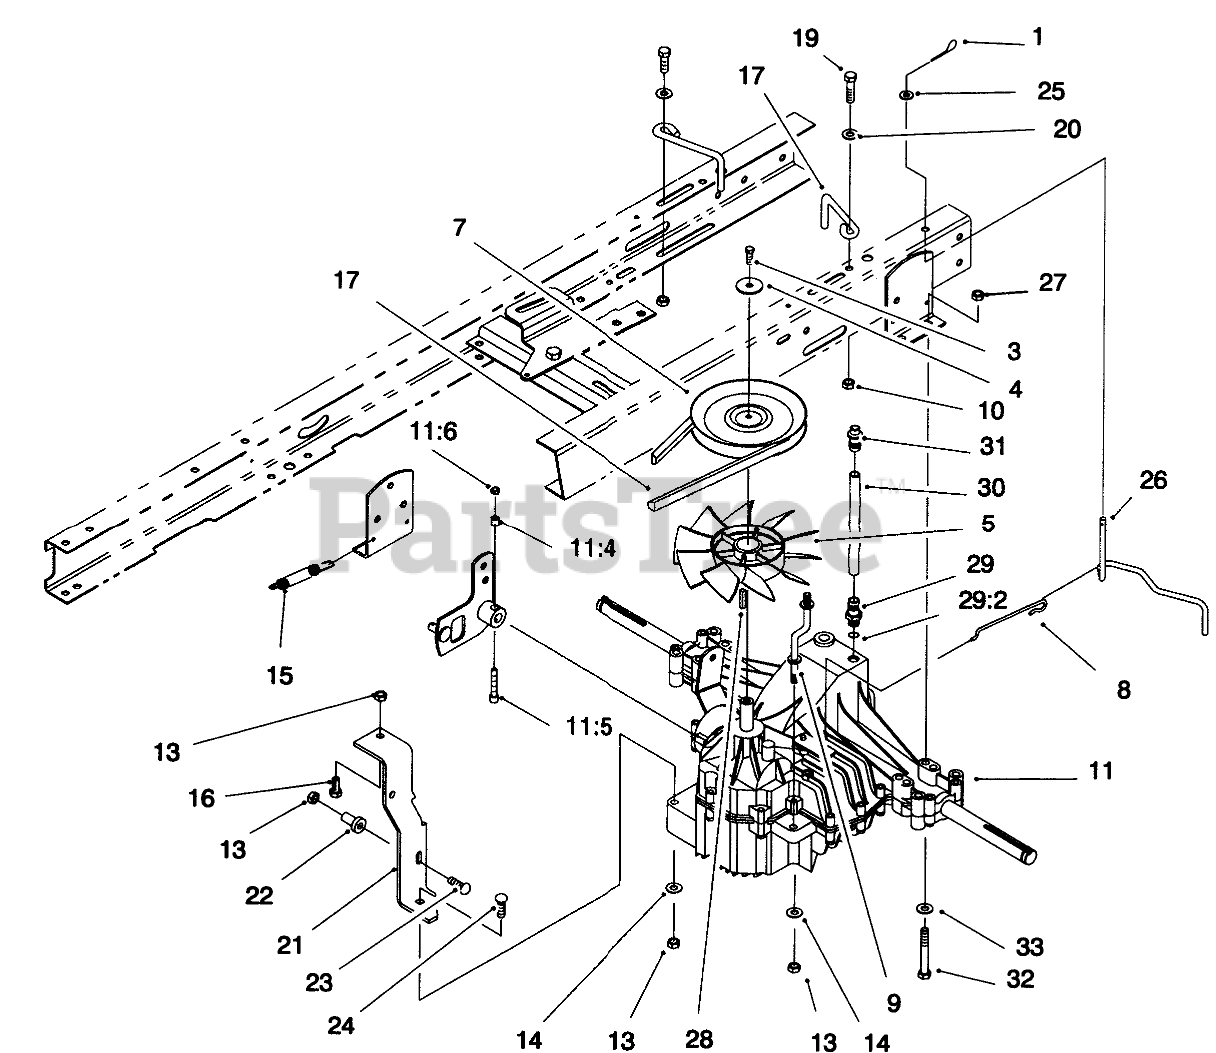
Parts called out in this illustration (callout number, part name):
1	PIN-COTTER
3	SCREW-HH
4	WASHER-FLAT
5	FAN - 10 BLADE 7" DIA.
7	PULLEY, TRANSMISSION
8	WIRE - BYPASS
9	STRAP - TORQUE
10	NUT-LOCK, NI
11	Transaxle Ass-y-Hydro
11:4	LOCK SPACER
11:5	SCREW-HSH
11:6	NUT-LOCK, NI
13	NUT-LOCK, NI
14	WASHER-PLAIN
15	SPRING-RETURN, BRAKE
17	GUIDE-BELT, TRANSMISSION
18	V-BELT, HYDRO
19	SCREW-HH
20	WASHER-PIVOT
21	Bracket-Speed Control
22	BUSHING-FLANGE
23	SCREW-CARR
24	BOLT-CARR
25	WASHER-FLAT
26	LEVER - BYPASS
27	NUT-LOCK, NI
28	KEY-PUMP
29	FITTING ASM
29:2	O-RING
30	HOSE, BREATHER
31	FITTING-VENT
32	SCREW-HH
33	WASHER-PLAIN
